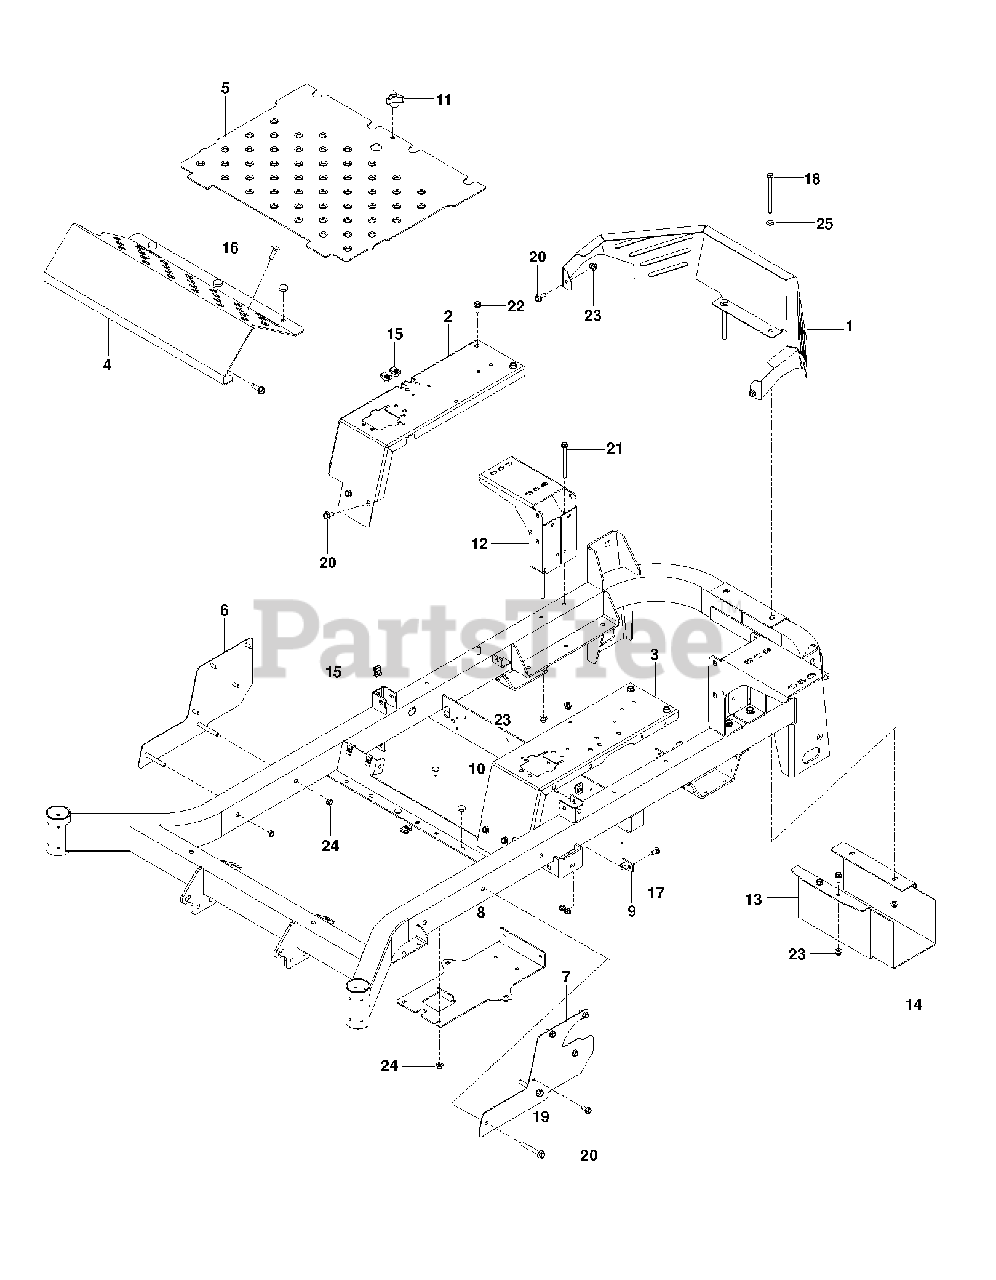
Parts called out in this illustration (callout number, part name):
2	PANEL.FILLER.RT.DIXON.BLUE
3	PANEL FILLER LT BLUE
8	PLATE, BATTERY, BLACK
9	STOP, DECK, EZ+
10	GROMMET, BUMPER
11	KNOB W/STUD
12	MOUNT, TANK, ZT BLK
13	SHIELD, MUFFLER, BLK
14	HEAT SHIELD
15	U-CLIP 5/16-18 NUT RETAINER
16	RHSNB 5/16C X 1
17	BOLT 5/16C X 3/4" CARRIAGE
18	HCS 5/16C X 4
19	HHFS 3/8-16 X 2 3/4
20	HHFS 5/16-18 X 3/4
21	HHFS 5/16-18 X 3 3/4
22	BLT 5/16-18 X 1 THRD FORM ZD
23	5/16-18 NYLOC FLANGE NUT
24	NUT HEX 3/8-16 NYLON, THIN
25	FLAT WASHER 5/16 SAE
